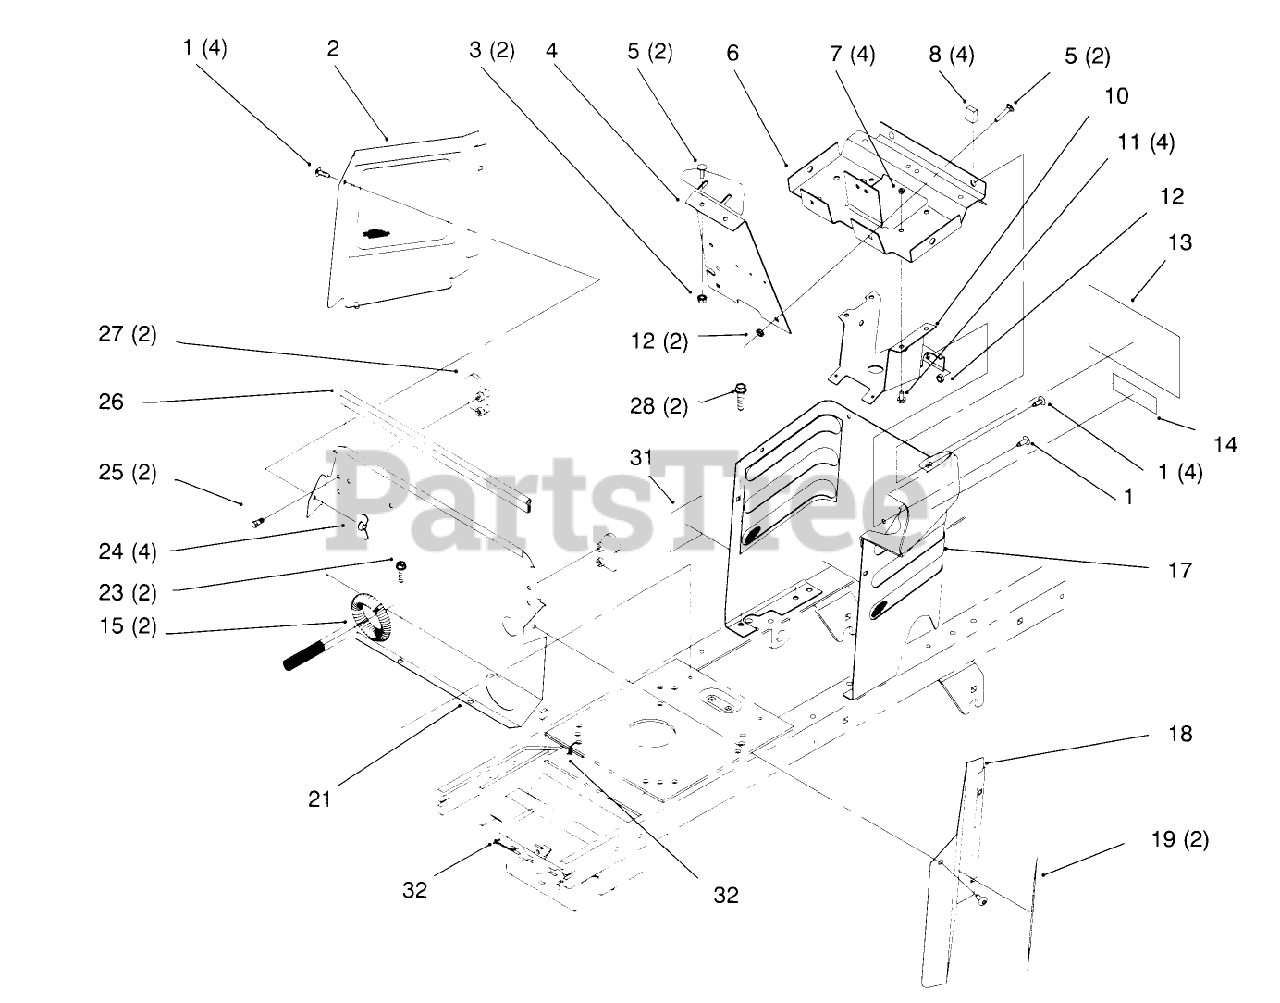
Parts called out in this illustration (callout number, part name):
1	SCREW-HH
2	RH SIDE COVER ASM
3	NUT-KEPS
4	PANEL-SUPPORT DASH
5	SCREW-CARR
6	SUPPORT-DASH
7	NUT-HEX
8	NUT RETAINER - J TYPE
10	BRACKET-COLUMN, LOWER
11	SCREW-HH
12	NUT-LOCK, NI
13	DECAL - DANGER
13	DECAL-DANGER
14	DECAL-INSTRUCTION
15	COVER-SHAFT, DRIVE
17	HOODSTAND W/DECALS
18	LH COVER ASM
19	DECAL, 264-G
19	DECAL - 264-H
19	Decal-268-H (Only On: 72103)
21	FIREWALL
23	SCREW-HWH
24	NUT-WING
25	SCREW-PLASTITE
26	TRIM-SEAL, FIREWALL
27	LATCH-HOOD
28	SCREW-HWHTF
32	TIE-CABLE
